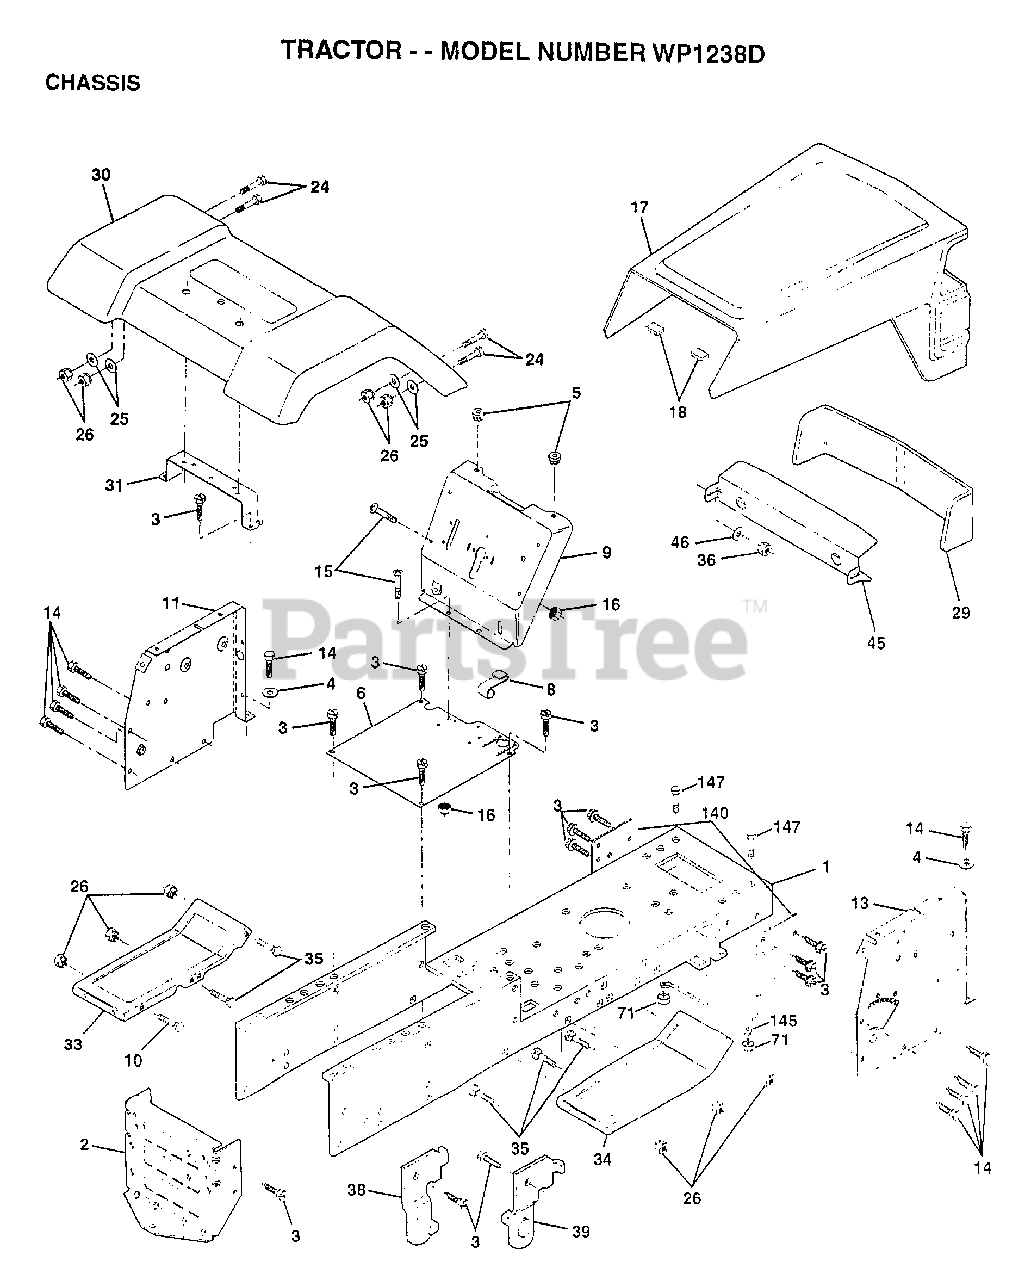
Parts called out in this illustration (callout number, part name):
1	CHASSIS ASM
3	SCREW
4	WASHER
5	BUMPER-HOOD/DASH
6	SADDLE
8	CLIP.RETAINER
9	DASH SILKSCR
11	"PANEL-DASH,LH"
14	SCREW LT
15	SCREW
17	HOOD/GRILL ASM
24	BOLT
25	WASHER
26	NUT
29	LENS SERVICE KIT
30	FENDER
31	BRKT FENDER
33	FOOTREST LH
34	FOOTREST RH
35	BOLT
36	PAL NUT LT
38	BRACKET ASM LH
39	BRACKET ASM RH
46	RETAINER
140	BRKT SUSPENSION
145	"ROD POVOT,CHASSIS"
147	BOLT LT
